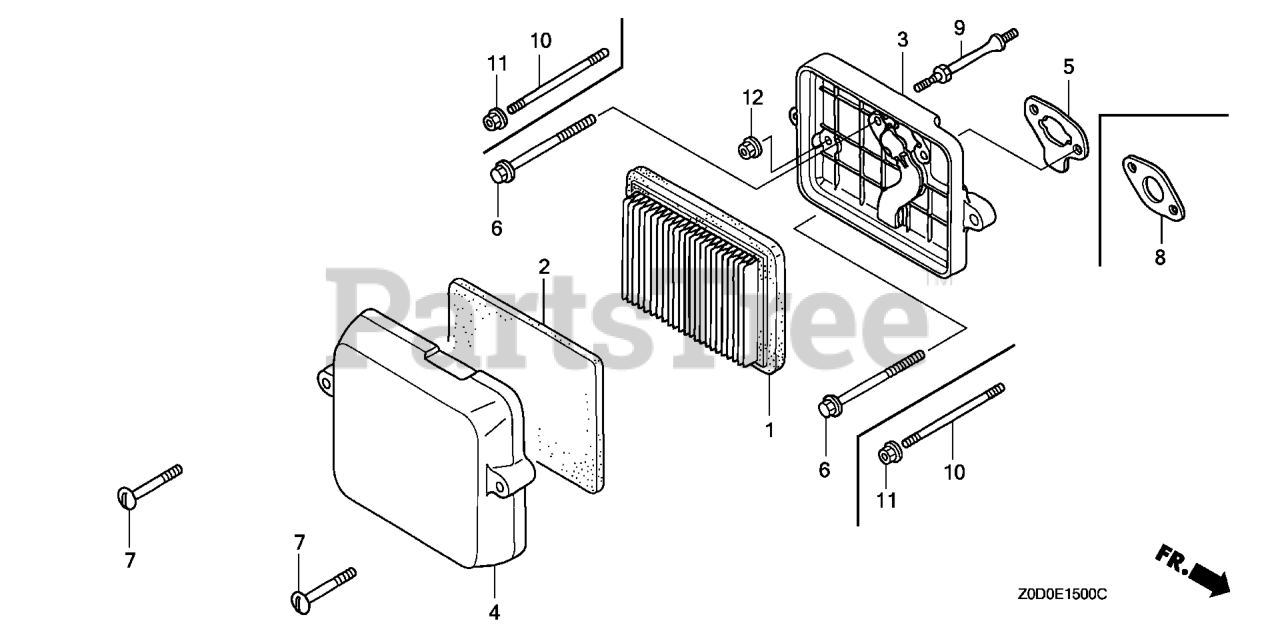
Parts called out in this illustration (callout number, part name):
1	ELEMENT, AIR CLEANER (TOYO ROKI) (ENGINE NO.)
2	FILTER (OUTER)
3	HOUSING, AIR CLEANER
4	COVER, AIR CLEANER
7	BOLT, AIR CLEANER COVER
8	GASKET, AIR CLEANER
9	BOLT, STUD
10	BOLT, STUD (5X85) (CT200)
11	NUT, FLANGE (5MM)
12	NUT, FLANGE (6MM)
